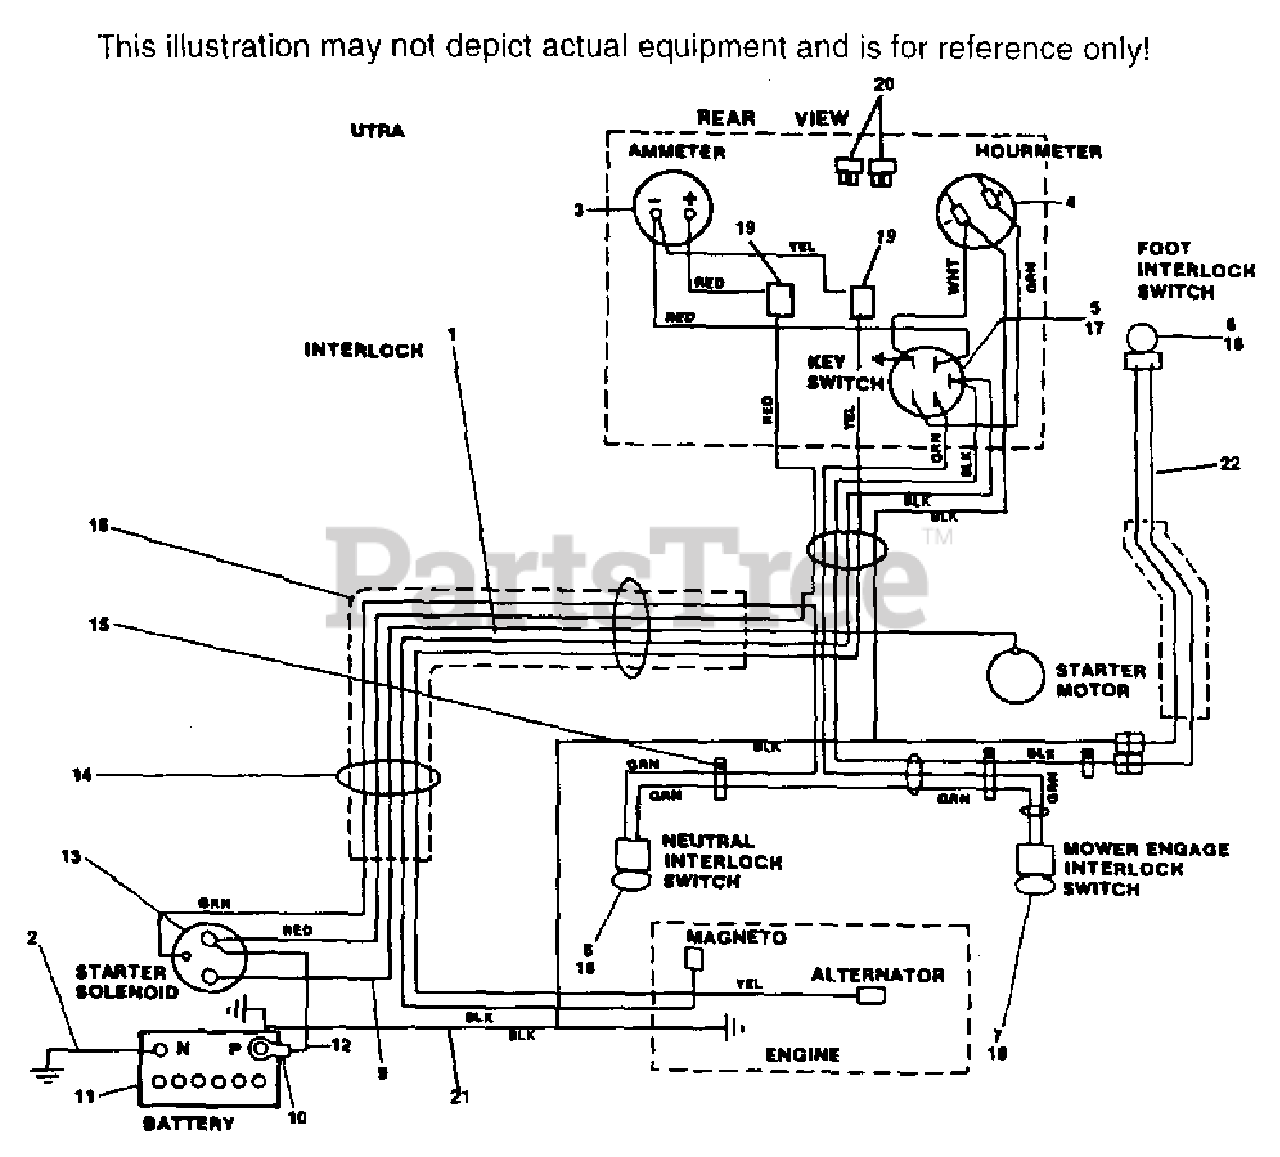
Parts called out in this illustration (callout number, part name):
1	WIRING HARNESS, COMPLETE
2	BATTERY CABLE, 20" BLACK
3	AMMETER
5	KEY SWITCH
6	FOOT INTERLOCK SWITCH
10	RUBBER BOOT
11	BATTERY
12	BATTERY CABLE, 13-3/4" RED
13	STARTER SOLENOID
14	CABLE TIE
15	CABLE CLAMP
16	PLASTIC CONDUIT
17	CONNECTOR, STARTER SWITCH
18	CONNECTOR, INTERLOCK SWITCH
19	WIRE ASSEMBLY W/FUSE
20	FUSES, 20 AMP BLADE TYPE
21	WIRE ASSEMBLY GROUND
22	WIRE, FOOT SWITCH
